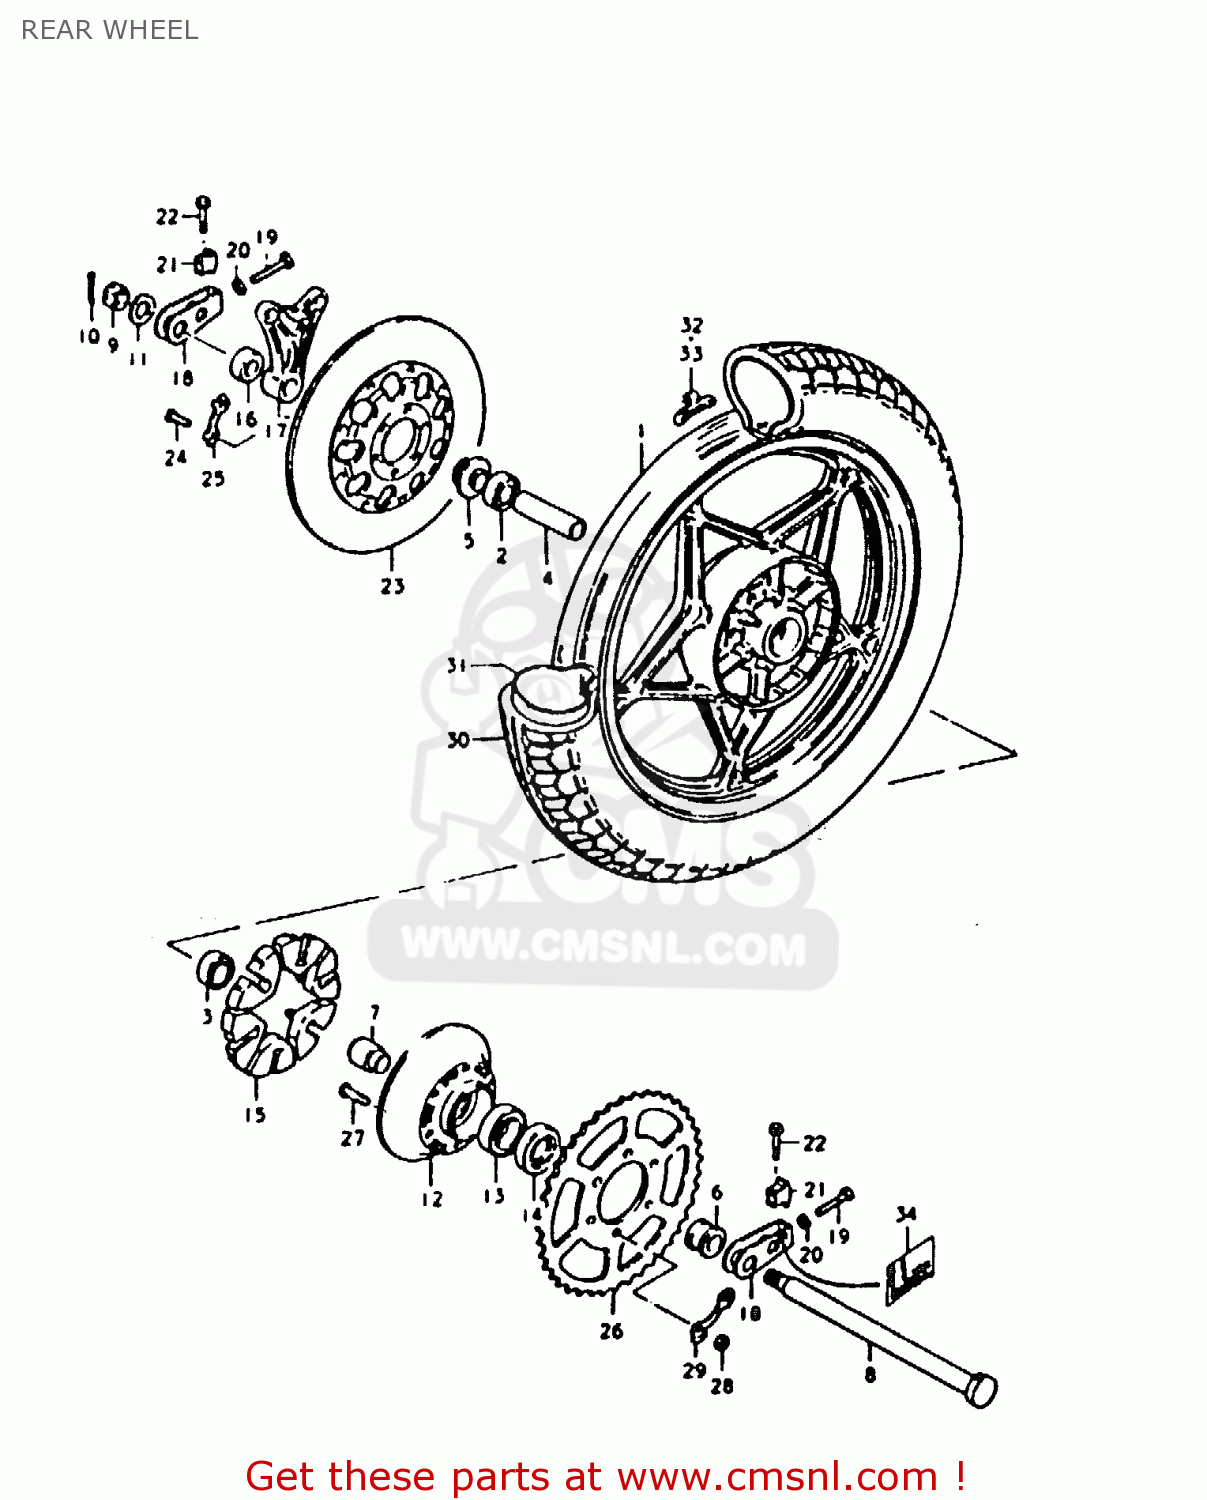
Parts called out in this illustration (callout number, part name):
1	WHEEL, REAR
2	BEARING WHEEL REAR(20X47X14)
3	BEARING, LH
4	SPACER,REAR HUB BEARING
5	SPACER,REAR AXLE
6	SPACER(20X33X28.3)
7	SPACER,REAR HUB BEARING
8	AXLE,REAR
9	NUT 18MM
10	PIN,COTTER
11	WASHER(19X34X4)
12	DRUM,REAR SPROCKET MOUNT
13	BEARING
14	SEAL,OIL(33X62X7)
15	ABSORBER,REAR HUB SHOCK
16	SPACER (20X38X17)
17	BRACKET,RR,CALIPER
18	ADJUSTER,CHAIN
19	BOLT
20	NUT
21	SUPPORTER,CHAIN ADJUST
22	BOLT (8X40)
23	DISC,BRAKE
24	BOLT 8X40
25	WASHER
26	SPROCKET,REAR
27	BOLT
28	NUT
29	WASHER
30	TIRE
31	TUBE ASSEMBLY,WHEEL,INNER
32	BALANCER,WHEEL
33	BALANCER,WHEEL
34	LABEL,CHAIN WEAR INDICATOR
